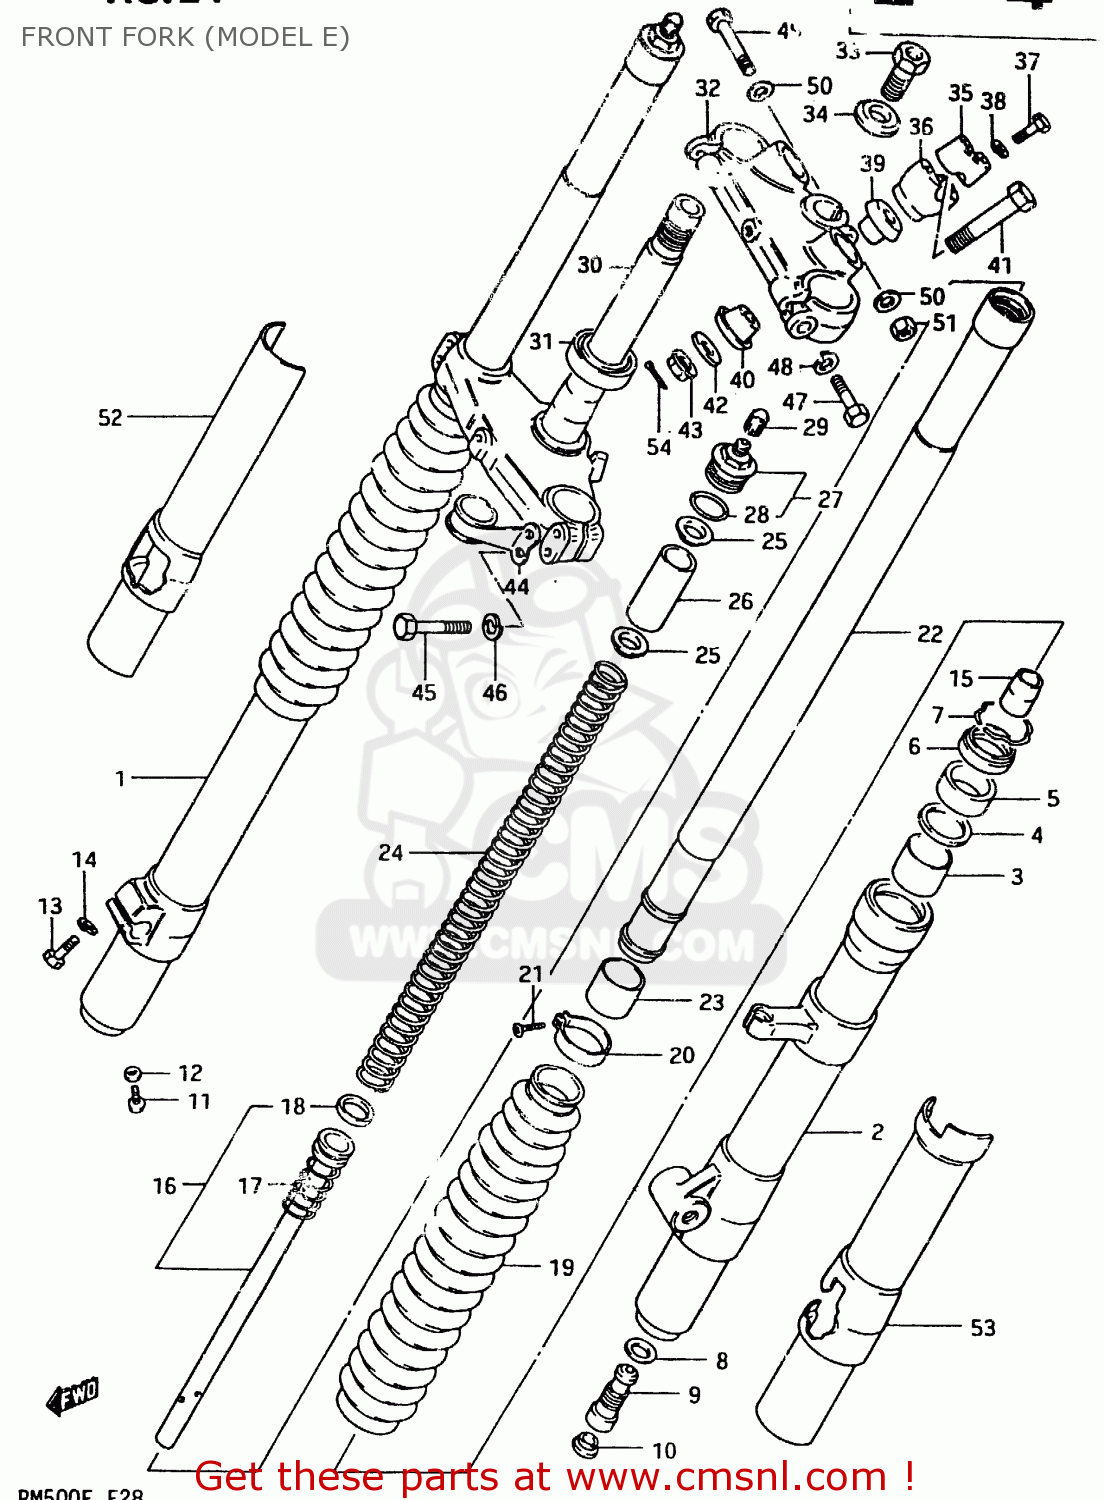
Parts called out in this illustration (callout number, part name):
1	TUBE,OUTER,RIGHT
2	TUBE,OUTER,LEFT
3	METAL,SLIDE
4	WASHER
5	SEAL,OIL
6	SEAL,DUST
7	RING,STOPPER
8	GASKET,FORK CYLINDER
9	VALVE,DF
10	CAP,FRONT FORK DF
11	SCREW 4X6
12	GASKET,DRAIN,PLUG (NAS)
13	BOLT (8X30)
14	WASHER,LOCK,8.
15	PIECE,FRONT FORK OIL LOCK
16	CYLINDER,FRONT FORK
17	SPRING,REBOUND
18	RING,FRONT FORK PISTON
19	BOOT,FRONT FORK COVER
20	BAND,BOOT,UPPER
21	SCREW 4X10
22	TUBE,FORK,INNER
23	PISTON
24	SPRING,FRONT FORK
25	GUIDE,FRONT FORK SPRING
26	SPACER,FRONT FORK SPRING
27	CAP,FORK INNER TUBE
28	O RING
29	CAP
30	STEM,STEERING
31	BEARING
32	HEAD,STEERING STEM
33	BOLT
34	WASHER
35	HOLDER,HANDLEBAR
36	HOLDER,HANDLE LWR
37	BOLT
38	WASHER,LOCK,8.
39	DAMPER,UPR
40	DAMPER,LWR
41	BOLT,HANDLE HOLDER
42	WASHER,HANDLEBAR HOLDER
43	NUT
44	GUIDE,CABLE
45	BOLT 8X40
46	WASHER,LOCK,8.
47	BOLT
48	LOCK WASHER
49	BOLT 8X50
50	WASHER
51	NUT
52	PROTECTOR,RIGHT
53	PROTECTOR
54	PIN 20X20
